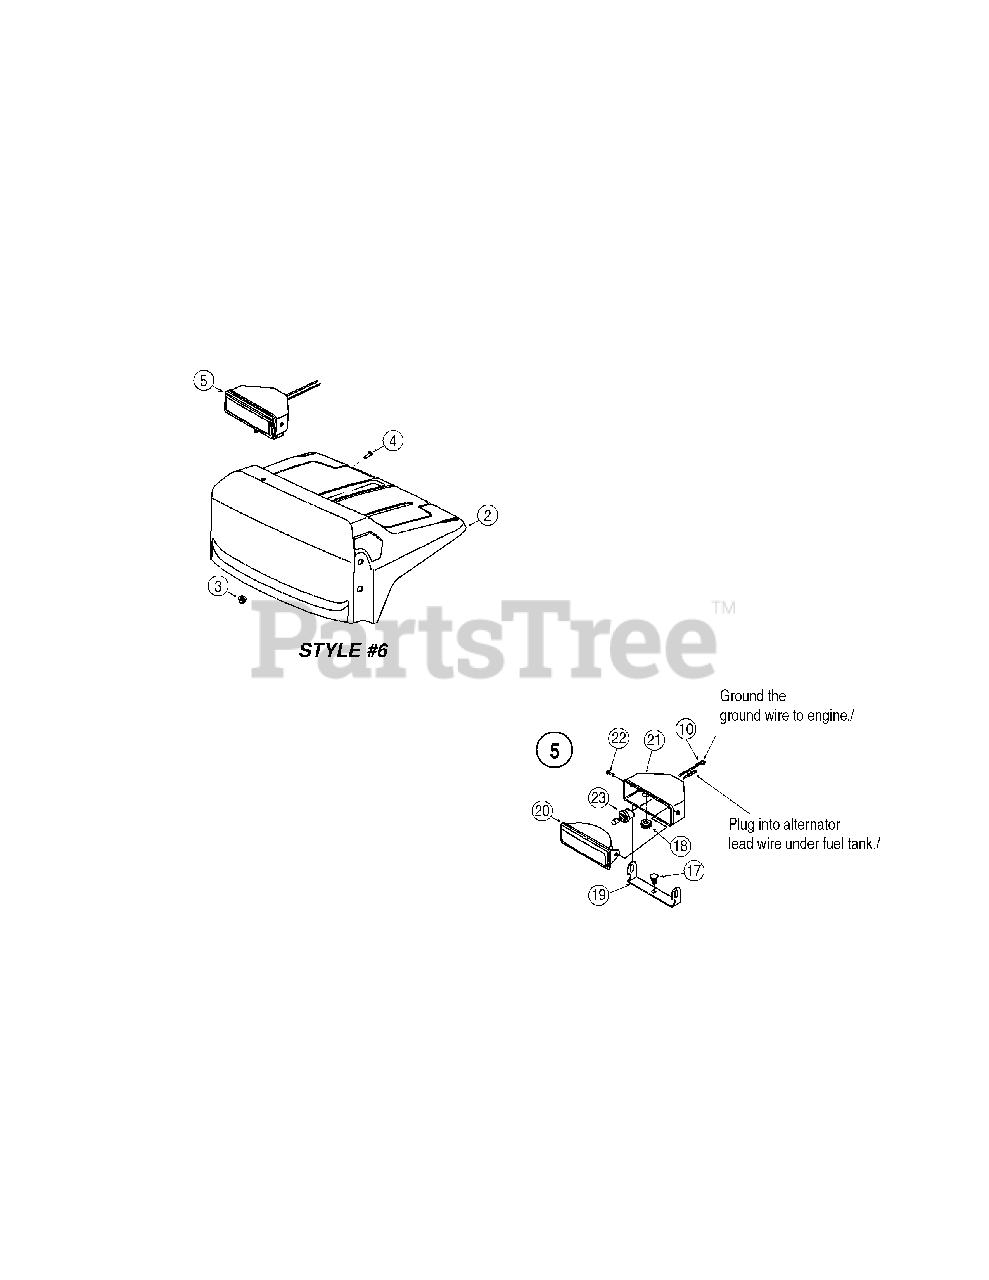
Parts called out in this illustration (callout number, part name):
2	Black Handle Panel STYLE 6
3	Hex Flange Locknut 5/16-18 Gr. F Nylon
4	Hex Tapp Wash Hd. Scr. #10 x 5/8
5	Top Mounting Halogen Lamp Assembly
17	Carriage Bolt 5/16-18 x .75
18	Grommet .38 ID X .50 OD X .12
19	Lamp Mounting Brkt.
20	Lamp/Lens Housing Ass’y
21	Halogen Lamp Housing
22	Phillips Pan Hd. Scr. M4 x 16mm
23	Bulb #890, 12 V, 27 Watt
